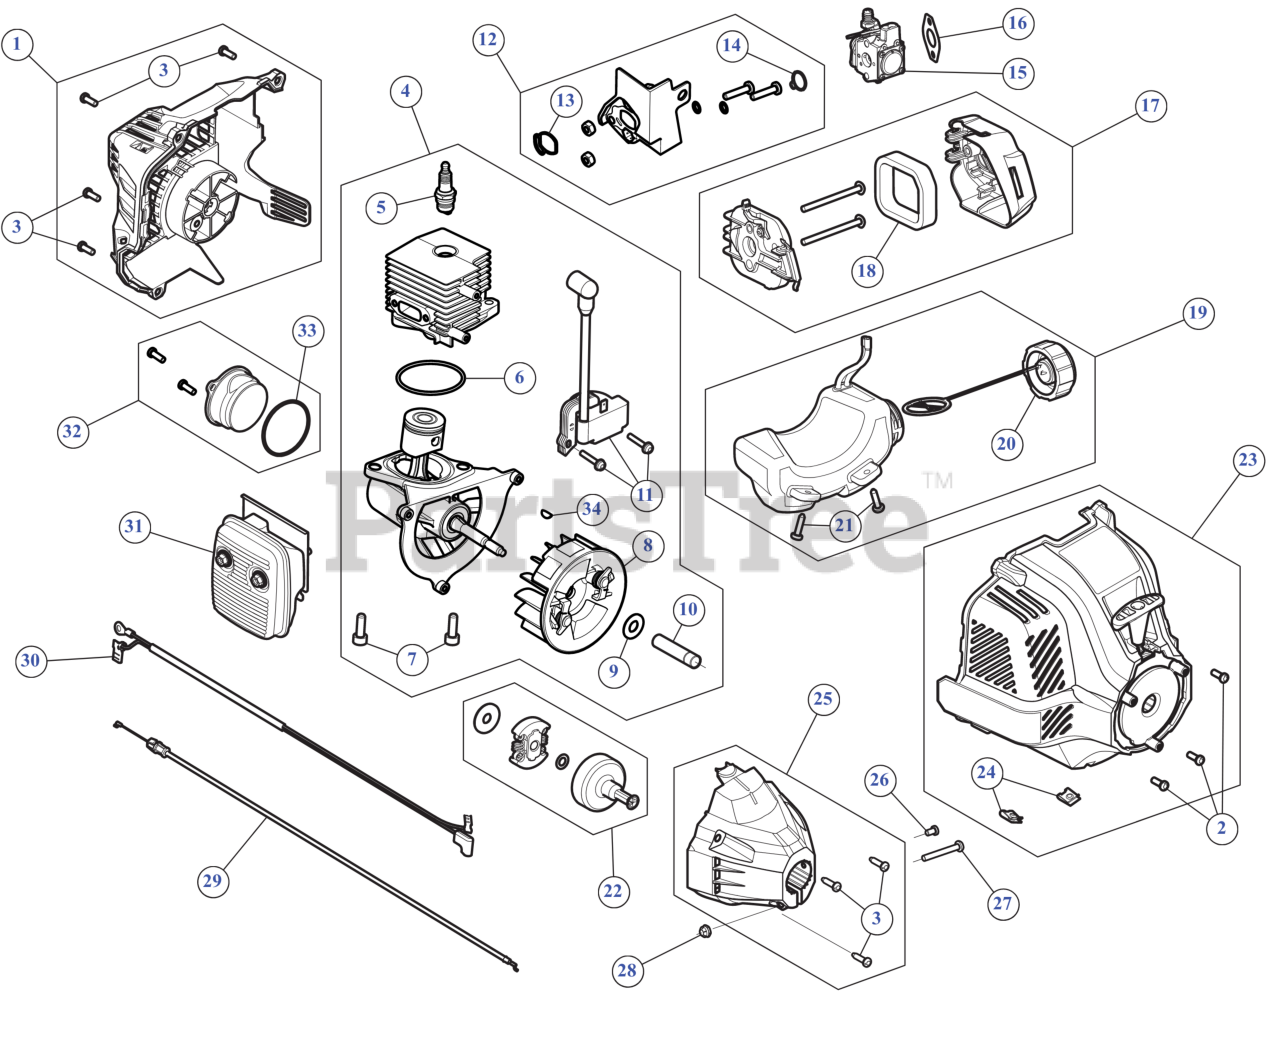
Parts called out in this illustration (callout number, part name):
1	REAR ENGINE COVER
2	SCREW #10-24X11/16 T-25
3	SCREW 8-16 x 3/4
4	SHORT BLOCK 25cc
5	SPARK PLUG
6	O-RING SEAL CYLINDER
7	SCREW 5/16-18x3/4 T40
8	FLYWHEEL ASSEMBLY
9	BELL WASHER
10	SPACER :2.165"
11	MODULE
12	INTAKE ASSEMBLY
13	INSL/CYL SEAL
14	CARBURETOR SEAL
15	CARBURETOR
16	GASKET CARB
17	AIR CLEANER COVER
18	AIR FLITER
19	FUEL TANK ASSEMBLY
20	FUEL CAP ASSEMBLY
21	SCREW:10-6 x .75
22	SMALL CLUTCH ASSEMBLY W/SMALL DRUM
23	STARTER HOUSING (LIBERTY RED)
24	NUT, TINNERMAN U-T
25	CLUTCH COVER
26	SCREW, 8-32 x .312 P
27	SCREW 10-24 X 1.12
28	HEX NUT
29	THROTTLE CABLE
30	LEAD WIRES
31	MUFFLER
32	CRANKCASE COVER
33	O-RING SEAL CRANKCASE
34	WOODRUFF KEY #403-.125 x .375
